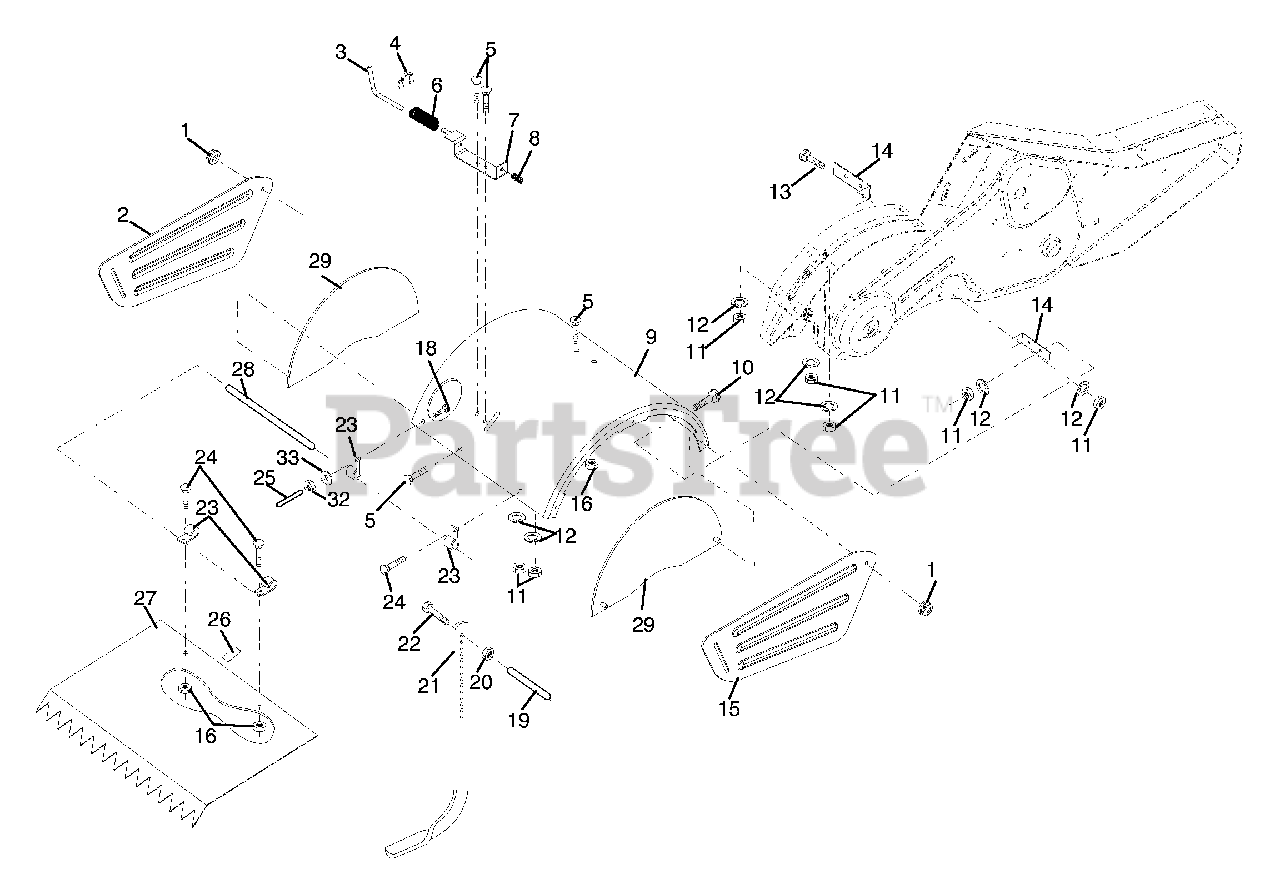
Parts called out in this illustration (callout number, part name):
1	Nut, Flange 5/16-18
2	Shield, Side, Outer L. H.
3	Pin, Stake, Depth
4	Ring, Klip
5	Bolt, Carriage 5/16-18 x 3/4
6	Spring
7	Bracket, Latch
8	Spring, Depth Stake
10	Bolt 5/16-18 x 1
11	Nut, Hex 5/16-18
12	Washer, Lock 5/16
13	Bolt, Carriage 5/16-18 x 1-1/4
14	Bracket, Shield Tine
15	Shield, Side, Outer R.H.
16	Nut, Hex Flange 1/4-20 unc
18	Bolt, Carriage 1/4-20 x 1-1/4 Gr. 5
19	Grip
20	Nut, Hex 3/8-16
21	Stake, Depth
22	Bolt, Hex 3/8-16 x 2
23	Hinge
24	Bolt, Carriage 1/4-20 x 1/2 Gr. 5
25	Cap, Vinyl
26	Pad, Idler
27	Shield, Leveling
28	Pin, Hinge
29	Shield, Side
32	Nut Fin Hex 1/4-20 unc
33	Washer Lock Hvy Helical 1/4
